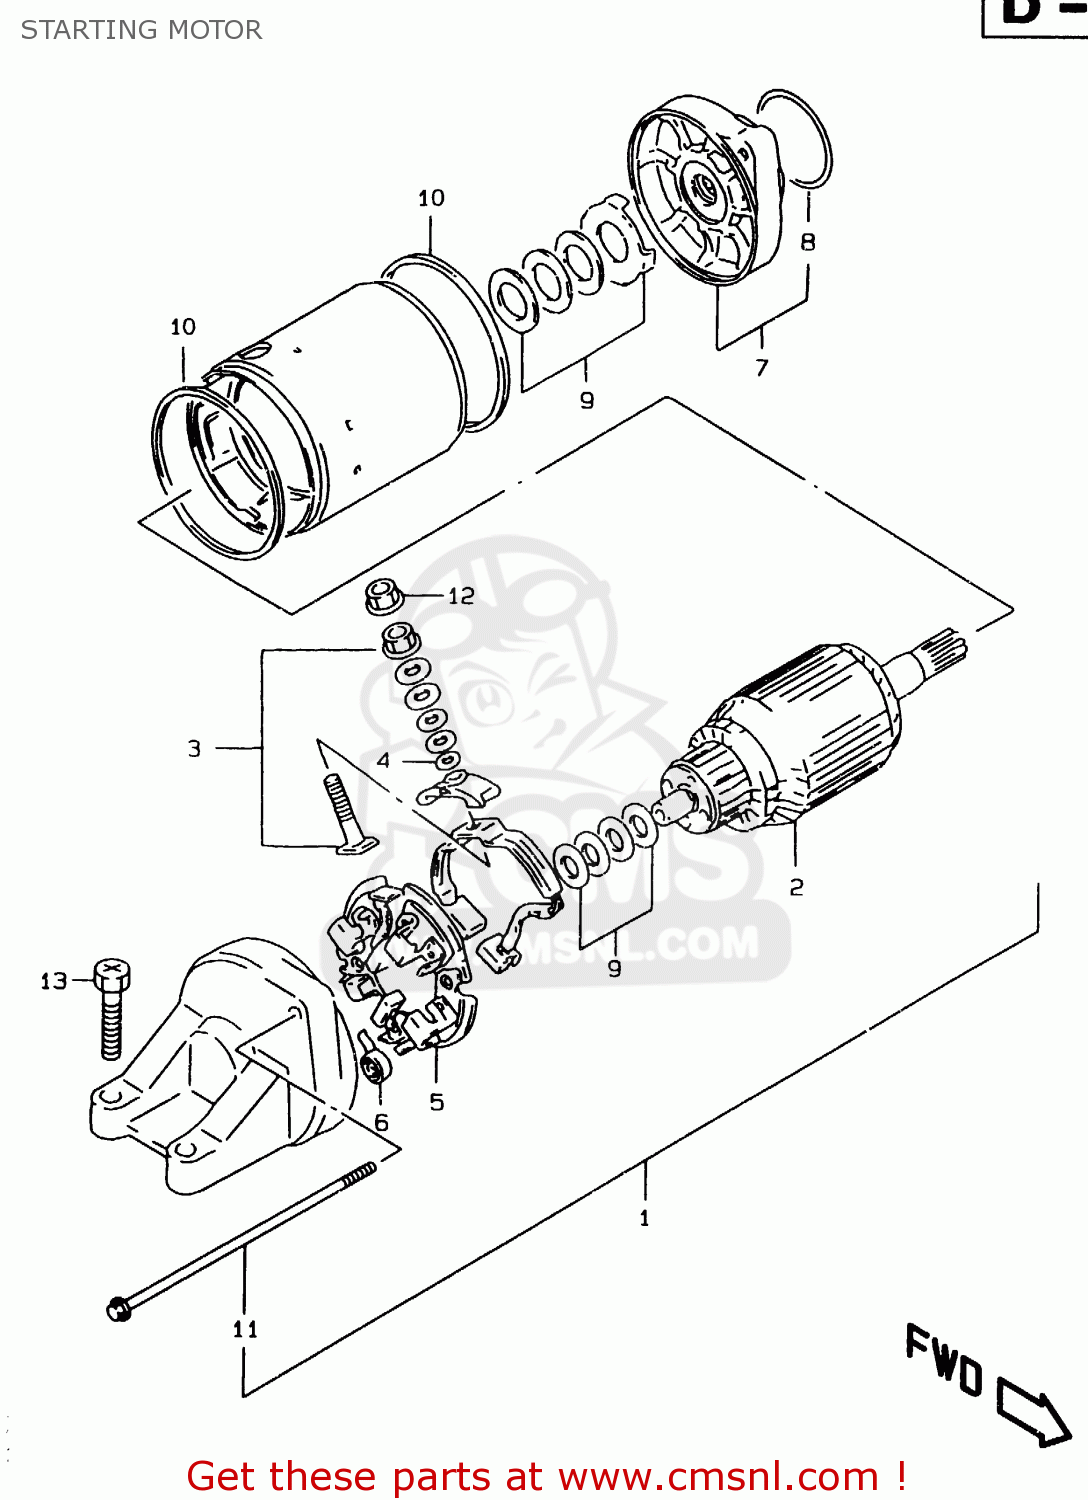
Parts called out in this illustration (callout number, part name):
1	MOTOR ASSY,STARTING
2	ARMATURE
3	TERMINAL SET,BRUSH
4	O RING
5	HOLDER SET,BRUSH
6	SPRING,BRUSH
7	BRACKET ASSY,FR
8	O RING
9	SHIM SET,STARTING MOTOR
10	O RING
11	BOLT
12	NUT
13	SCREW (6X25)
